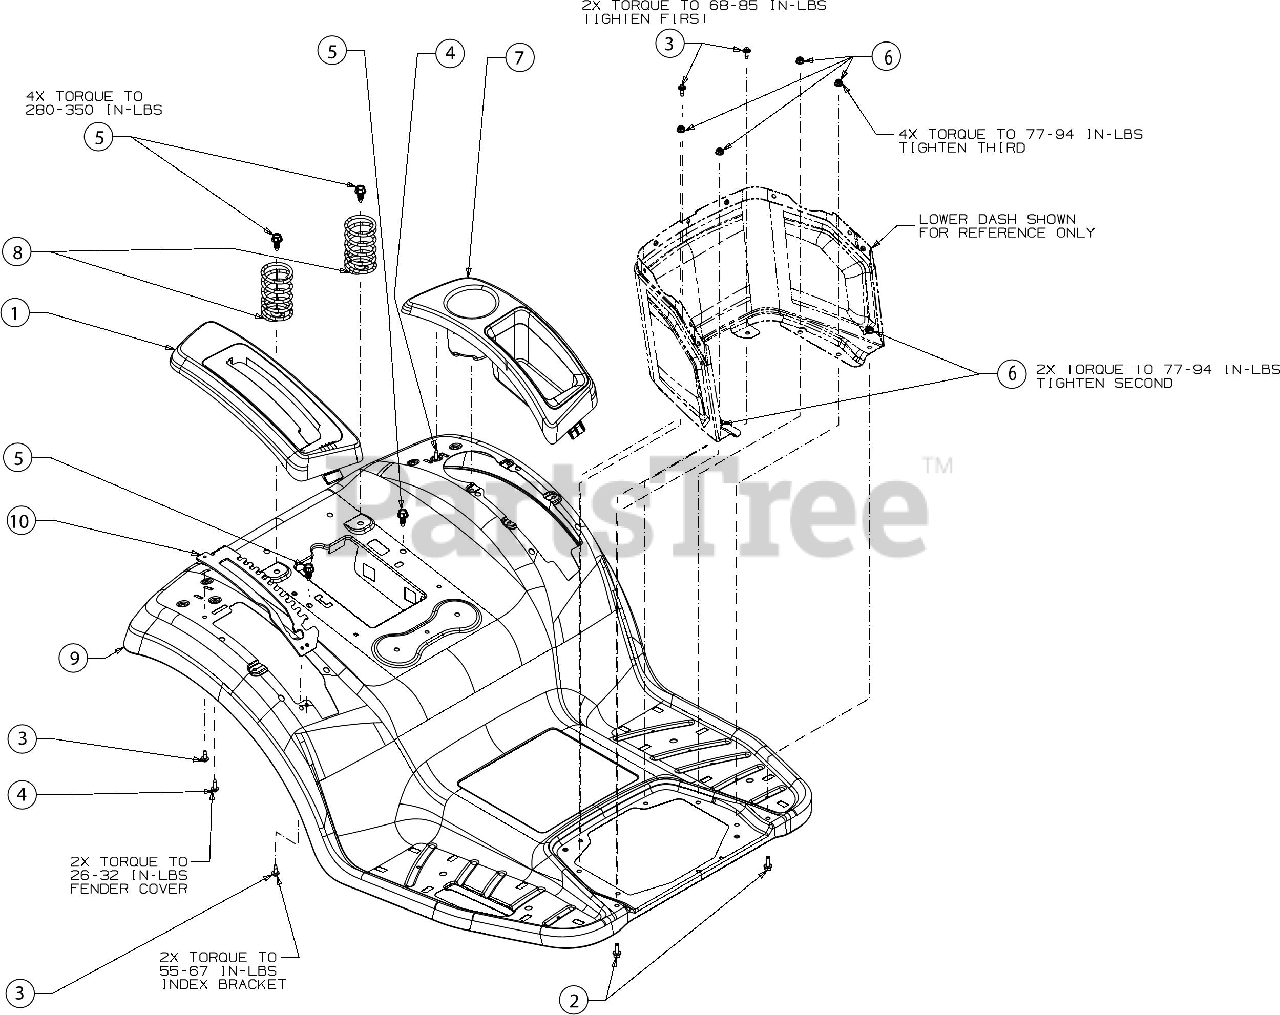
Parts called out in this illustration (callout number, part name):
1	FENDER COVER (RH)
2	SCREW 1/4-20 X .75 GR5
3	SCREW M6-1 X .625
4	SCREW 1/4-10 X .750
5	HEX SCREW WASH TT 3/8-16 X .875
6	FLANGE LOCK NUT
7	FENDER COVER (LH)
8	COMPRESSION SPRING
9	REAR FENDER
10	LIFT INDEX BRACKET
